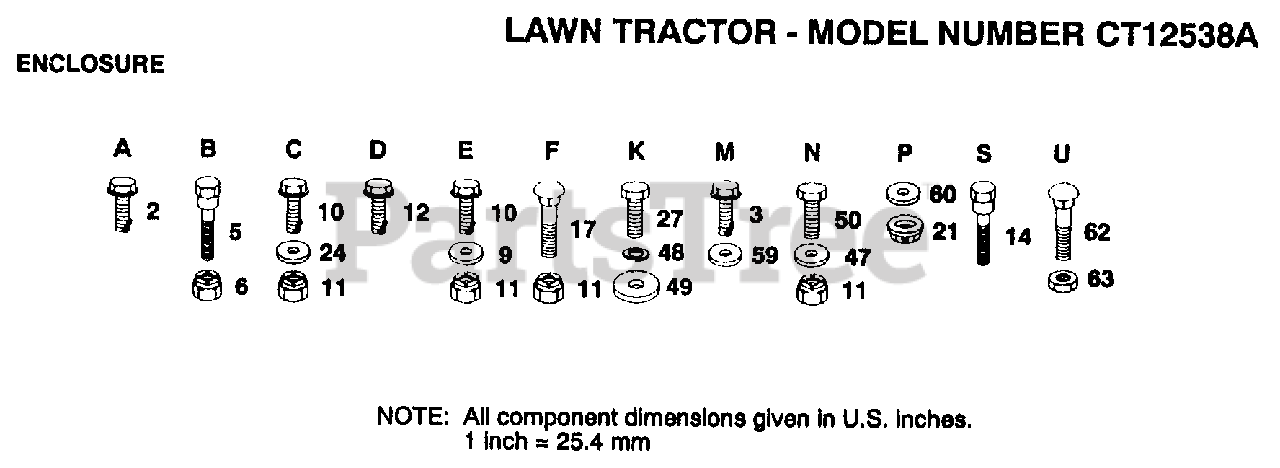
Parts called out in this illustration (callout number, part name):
2	SCREW
3	SCREW GTV
9	WASHER
12	SCREW LT
14	"BOLT,SHOULDER"
17	BOLT
21	PAL NUT LT
24	WASHER
27	BOLT
47	WASHER
48	LOCKWASHER
49	WASHER
50	BOLT
59	WASHER
60	WASHER PM
62	BOLT
